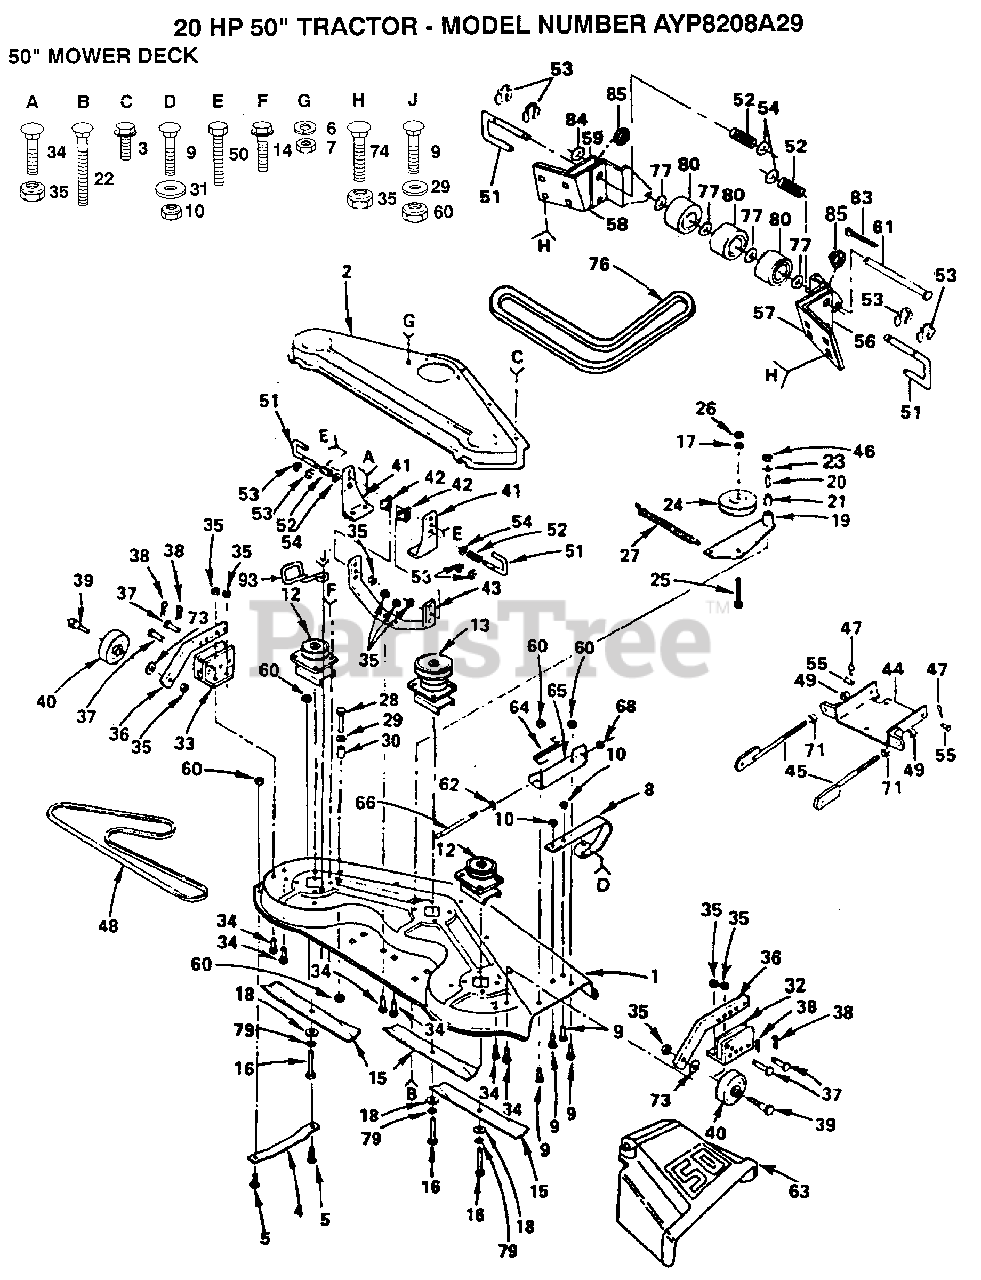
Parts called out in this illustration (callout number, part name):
2	CVR DRIVE DECK
3	SCREW LT
4	RUNNER-LH M
5	BOLT
6	LOCKWASHER
7	NUT.HEX.5/16-18
9	BOLT
13	JACKSHAFT
14	SCREW
15	"BLADE.50""STD.LIFT"
16	BOLT.3/8-24X1-1/2
17	LOCKWASHER
18	WASHER
19	ARM ASSY GT
22	BOLT
24	IDLER-FLAT T
26	NUT.HEX.3/8-16UNC
27	SPRING T
28	BOLT
29	WASHER M
30	SPACER SPLIT LT
31	WASHER
32	GUAGE WHL BRKT GT
33	GUAGE WHL BRKT GT
34	BOLT
36	GUAGE WHL BAR GT
39	BOLT M
40	WHEEL.GAGE.BLK.PL
41	SUSP BRKT GT
42	SPACER GT
43	SUSP BRACE GT
45	BRACKET.SUSPEN.AS
46	JAM NUT TI
47	RETAINER.SPRING
48	V-BELT M
49	NUT LTV
50	BOLT
51	RELEASE PIN GT
52	SPRING M
53	KLIP RING
55	CLEVIS PIN GT
56	BRACKET T
57	BRACKET T
58	BRACKET T
59	BRACKET T
61	PIVOT PIN T
62	WASHER
63	DEFLECTOR
66	ROD-HINGE T
68	NUT PUSH M
71	NUT
73	WASHER
74	BOLT
76	BELT-V.93.5.MWR
77	WASHER T
80	ROLLER T
83	COTTER PIN
85	SPACER T
93	BELT RETIANER
